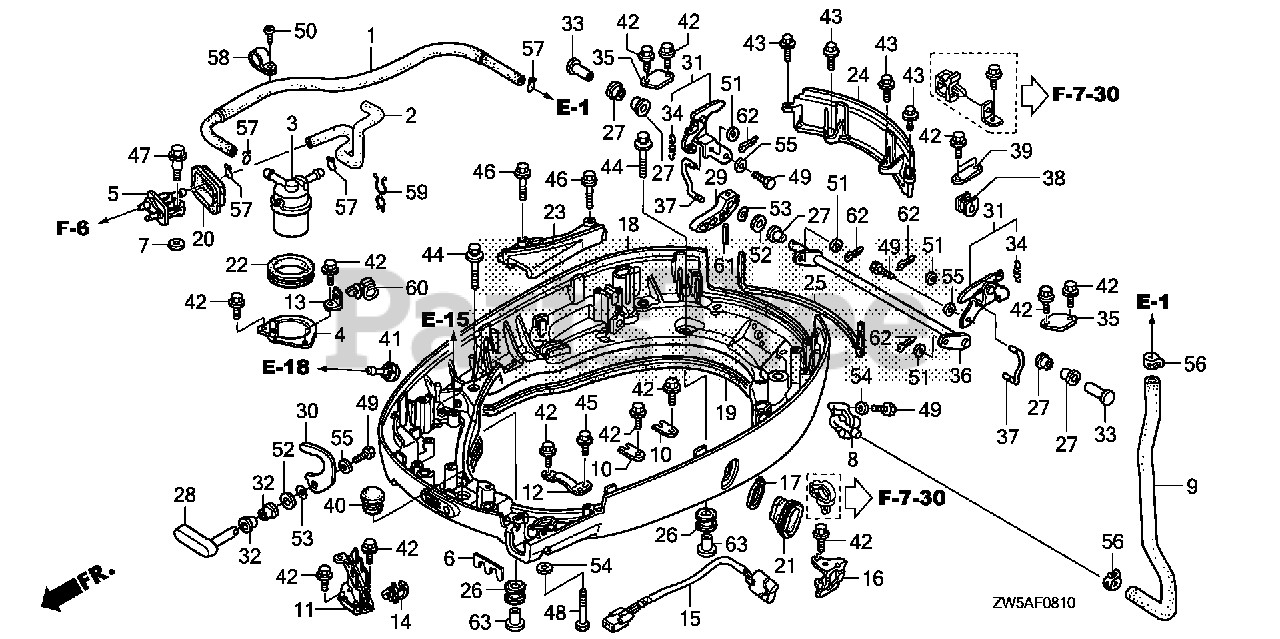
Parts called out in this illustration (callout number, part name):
1	TUBE, FUEL
2	TUBE B, FUEL
3	STRAINER, FUEL
4	STAY, FUEL STRAINER
5	CONNECTOR ASSY., FUEL (B)
6	PLATE, REMOTE CONTROL CABLE
7	WASHER, PIVOT
8	JOINT, WATER INLET
9	HOSE, FLUSHING WATER
10	PLATE, SHIFT SHAFT
11	BRACKET, CONNECTOR (B)
12	BRACKET, CABLE CLIP (S)
13	BRACKET, CLIP (C)
14	CLAMP, WIRE
15	SWITCH ASSY., POWER TRIM-TILT
16	STAY, POWER TILT SWITCH
17	BAND (BLACK 3.5X140)
18	CASE, ENGINE (LOWER) *NH282MU* (OYSTER SILVER METALLIC-U)
19	SEAL, CASE (LOWER)
20	GROMMET, CASE (LOWER) (B)
21	GROMMET, CASE (LOWER) (G)
21	GROMMET, CASE (LOWER)
22	GROMMET, FUEL STRAINER
23	CASE, SEPARATE *NH282MU* (OYSTER SILVER METALLIC-U)
24	CASE, RR. SEPARATOR *NH282MU* (OYSTER SILVER METALLIC-U)
25	SEAL, SEPARATOR CASE
26	RUBBER, FR. CARRIER CUSHION
27	BUSH (14X10)
28	LEVER, COVER LOCK *NH282MU* (OYSTER SILVER METALLIC-U)
29	LEVER, COVER LOCK
30	HOOK, COVER LOCK
31	HOOK, COVER LOCK
32	BUSH, COVER LOCK
33	SHAFT, COVER B LOCK
34	SPRING, COVER LOCK HOOK
35	PLATE, COVER LOCK SHAFT
36	SHAFT, COVER LOCK
37	ROD, COVER LOCK
38	BUSH, COVER LOCK SHAFT
39	PLATE, COVER B LOCK SHAFT
40	CAP, L. SIDE COVER
41	GROMMET, WATER CHECK
42	BOLT, FLANGE (6X12) (CT200)
43	BOLT, FLANGE (6X20) (CT200)
44	BOLT-WASHER (8X35)
45	BOLT, FLANGE (5X10) (CT200)
46	BOLT, FLANGE (6X30)
47	BOLT, SPECIAL (6X22) (CT200)
48	BOLT, HEX. (6X40)
49	BOLT, HEX. (6X16)
50	SCREW, RIVET (5X10)
51	WASHER, PLAIN (5MM)
52	WASHER (14MM)
53	WASHER, WAVE (14MM)
54	WASHER, PLAIN (6MM)
55	WASHER (6MM)
56	CLAMP, TUBE (D18.8)
57	CLIP, TUBE (B12)
58	CLIP (14MM)
59	CLIP, PURSE LOCK
60	CLIP, HARNESS
61	PIN, SPRING (6X22)
62	PIN, SPLIT (2.0)
63	COLLAR (8.5X14.5)
